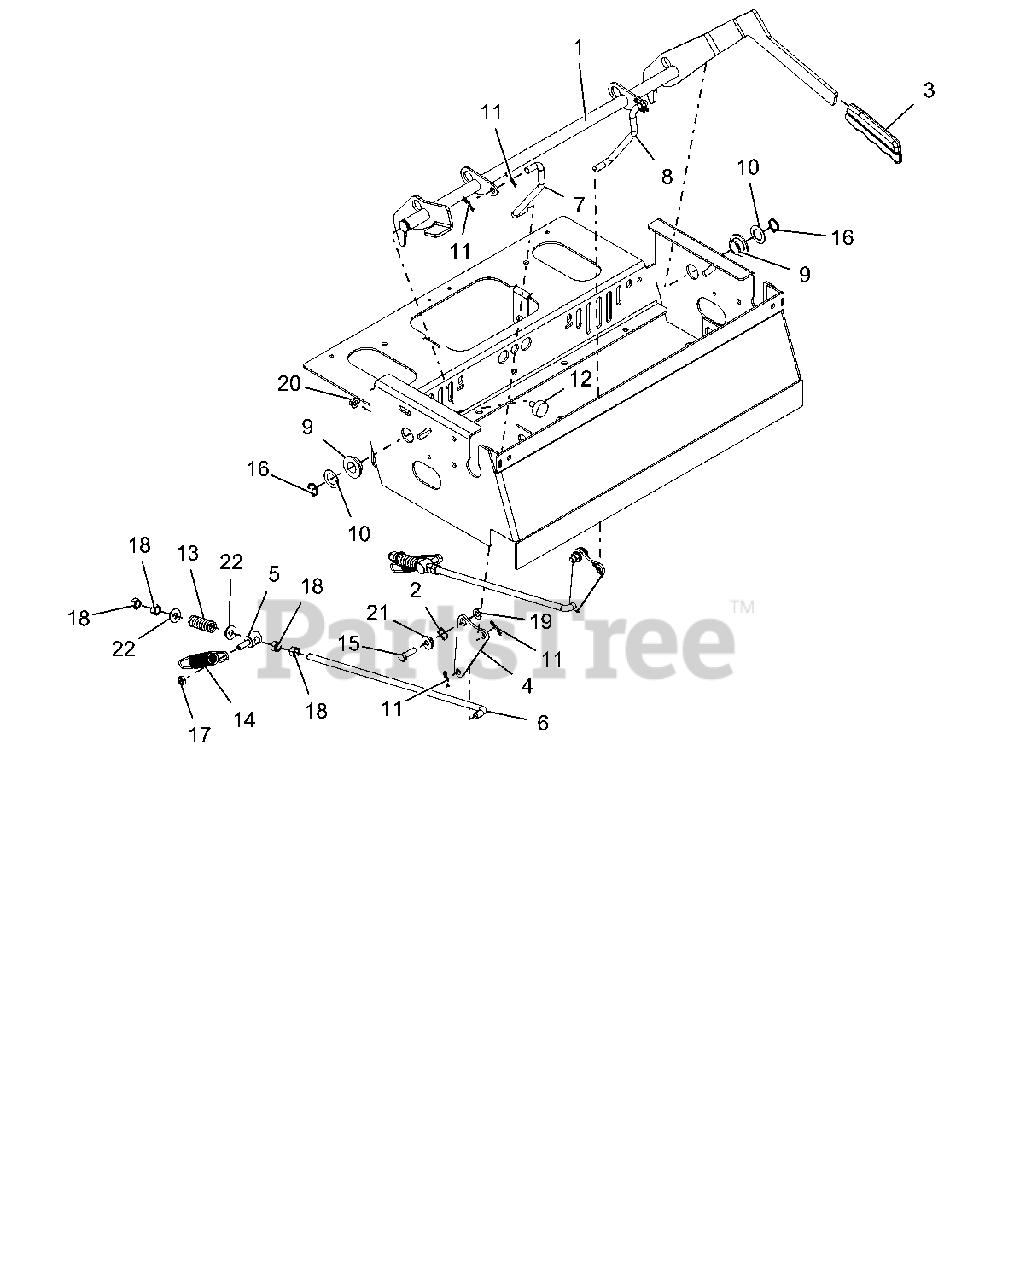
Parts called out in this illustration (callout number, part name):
1	WLDMT,PT200/400 PARK BRAKE-GAS
2	WAVE WASHER .531X.781X.125FH
3	GRIP, PARKING BRAKE (YELLOW)
4	PLATE, BRAKE PIVOT
5	TRUNNION, .38-16
6	ROD, BRAKE ADJ.
7	LINKAGE, RH BRAKE ACTUATING
8	LINKAGE, LH BRAKE ACTUATING
9	BSHG-FLG .762X1.48X.44 NYL
10	WSHR-HDND-THRST .758X1.23X.031
11	PIN-HAIR, ENDRIES #25 YWZC
12	BUMPER, RUBBER
13	SG-COMP .142 X .710 X 1.75
14	SPRING-TENS .105X.850X.4.880
15	@BLT-HEX .31-18X1.00 GR5 YWZC
16	RG-RTNG-EXT .689X.078
17	NUT-LK-CTR-JAM .31-18 YWZC
18	@NUT-HEX .38-16 YWZC
19	NUT-LK-TOP-FLG .31-18 YWZC
20	NUT-SPNLK-FLG .312-18 YWZC
21	BSHG-FLG .32X.500X.344X.880
22	WSHR-FL-STL.38X.875X.083 YWZC
